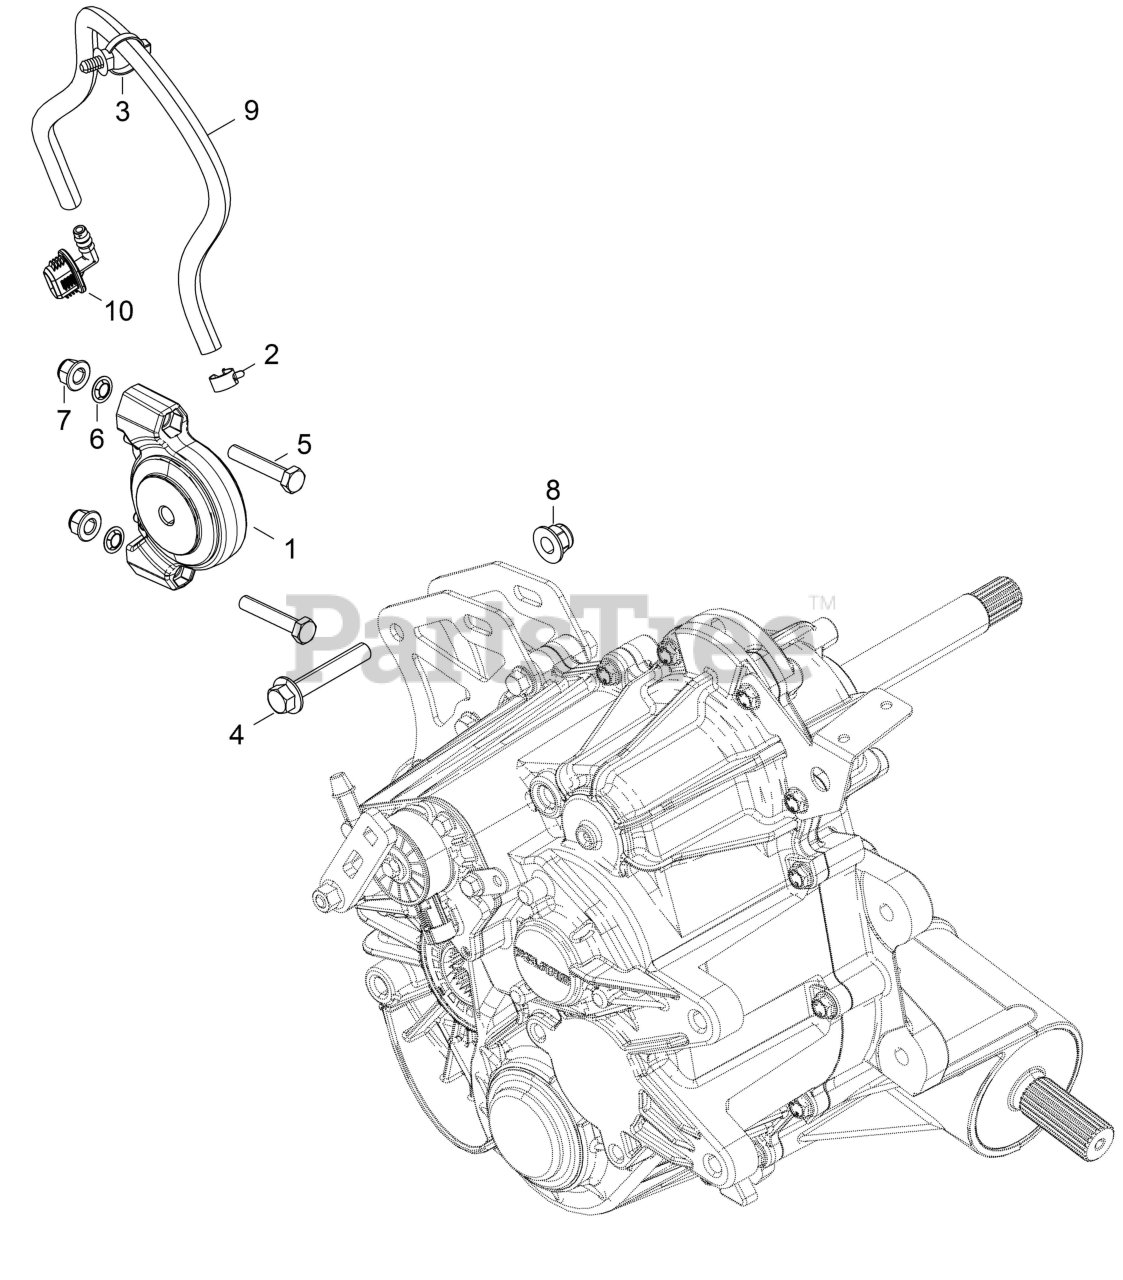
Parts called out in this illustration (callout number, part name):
1	MOUNT-ISOLATOR,DRIVELINE
2	CLAMP-HOSE, 17/32, GREEN
3	CLIP-ROUTING
4	BOLT-M10X1.25X60,HXFLG-OLIVE D
5	SCR-HH M8X1.25X45 8.8 ZOD
7	NUT-M8X1.25,FLG,NYLOC-OLIVE D
8	NUT-M10X1.25,FLG,NYLOC-OLIVE D
9	LINE, FUEL 54 CM
10	FITTING, VENT LINE, 90
